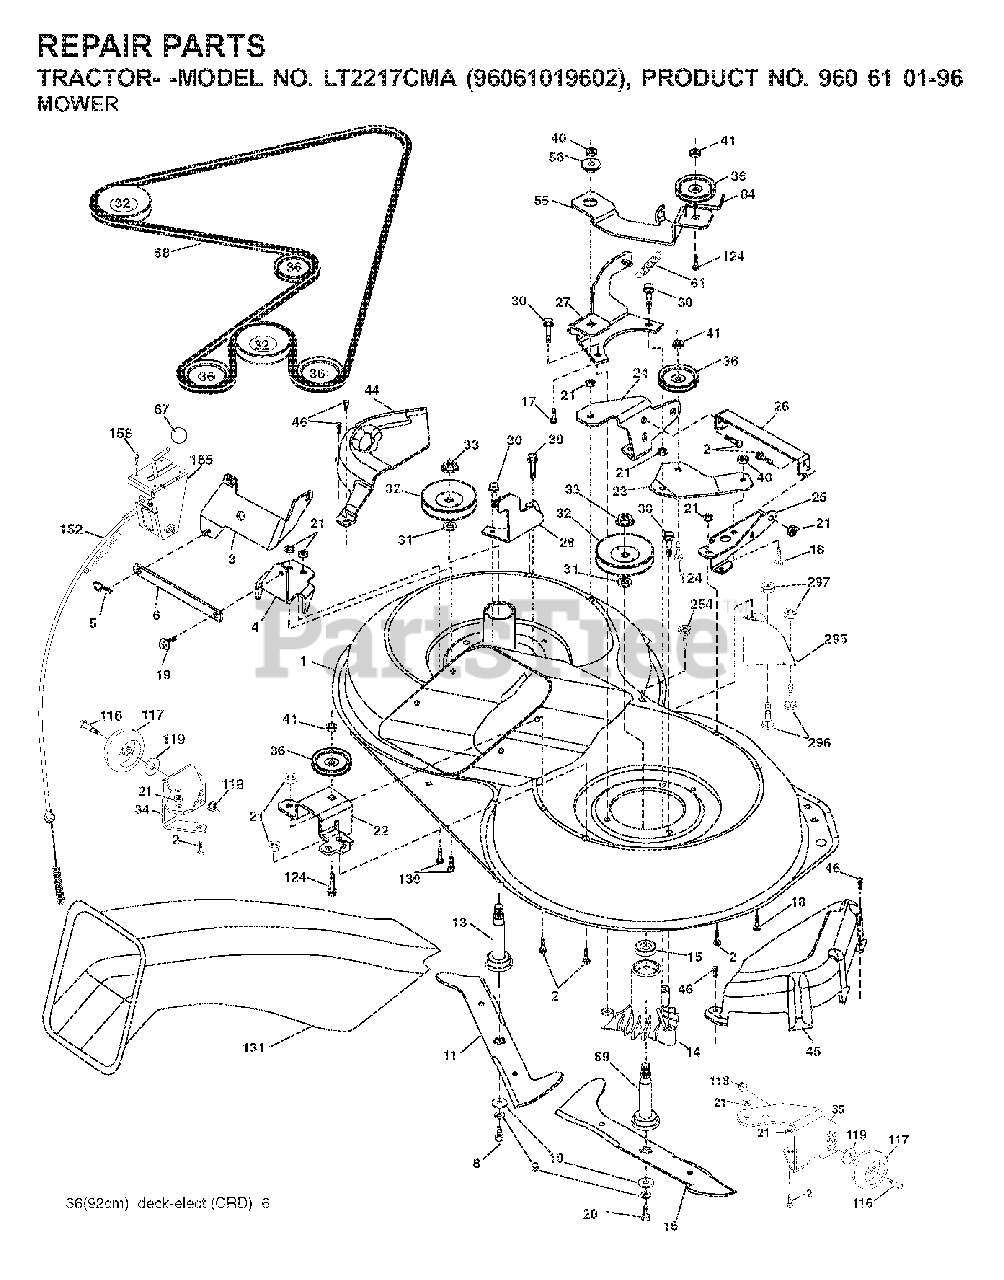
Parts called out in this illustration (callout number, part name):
2	BOLT
3	BRACKET
5	RETAINER-SPRNG RB
6	BAR SWAY
9	LOCKWASHER
10	WASHER.BLADE
13	SHAFT ASM VENT
14	HSG MANDREL
17	BOLT.3/8-14X1.25
19	BOLT SHD 5/16-18
21	LOCKNUT
24	BRACKET
25	BRACKET
28	BRACKET
30	SCREW, WASHER HEAD
31	WASHER.SPACER.MANDREL
32	PULLEY MANDREL
33	NUT.FLANGE.LOCK.TOP
36	PULLEY.IDLER.4.25
40	LOCKNUT
41	NUT LOCK FLG 3/8-16 UNC
45	MANDREL COVER
46	SCREW.1/4-20X5/8
56	SPACER.RETAINER.MOWER
67	KNOB T (3/8 HOLE)
69	SHAFT.ASM.W/LWR.BRG.RH.THREAD
84	KEEPER, BELT IDLER
116	BOLT.SHOULDER.3/8-16X3-5/8
117	WHEEL. GUAGE RALLY
118	NUT LOCK FLG 3/8-16 UNC
124	BOLT.3/8-16X1.50
131	CHUTE BAGGER
158	SCREW
185	HEAD ASM. CABLE CLUTCH
254	SCREW 3/8-16X1
296	BOLT
297	NUT CENTERLOCK
